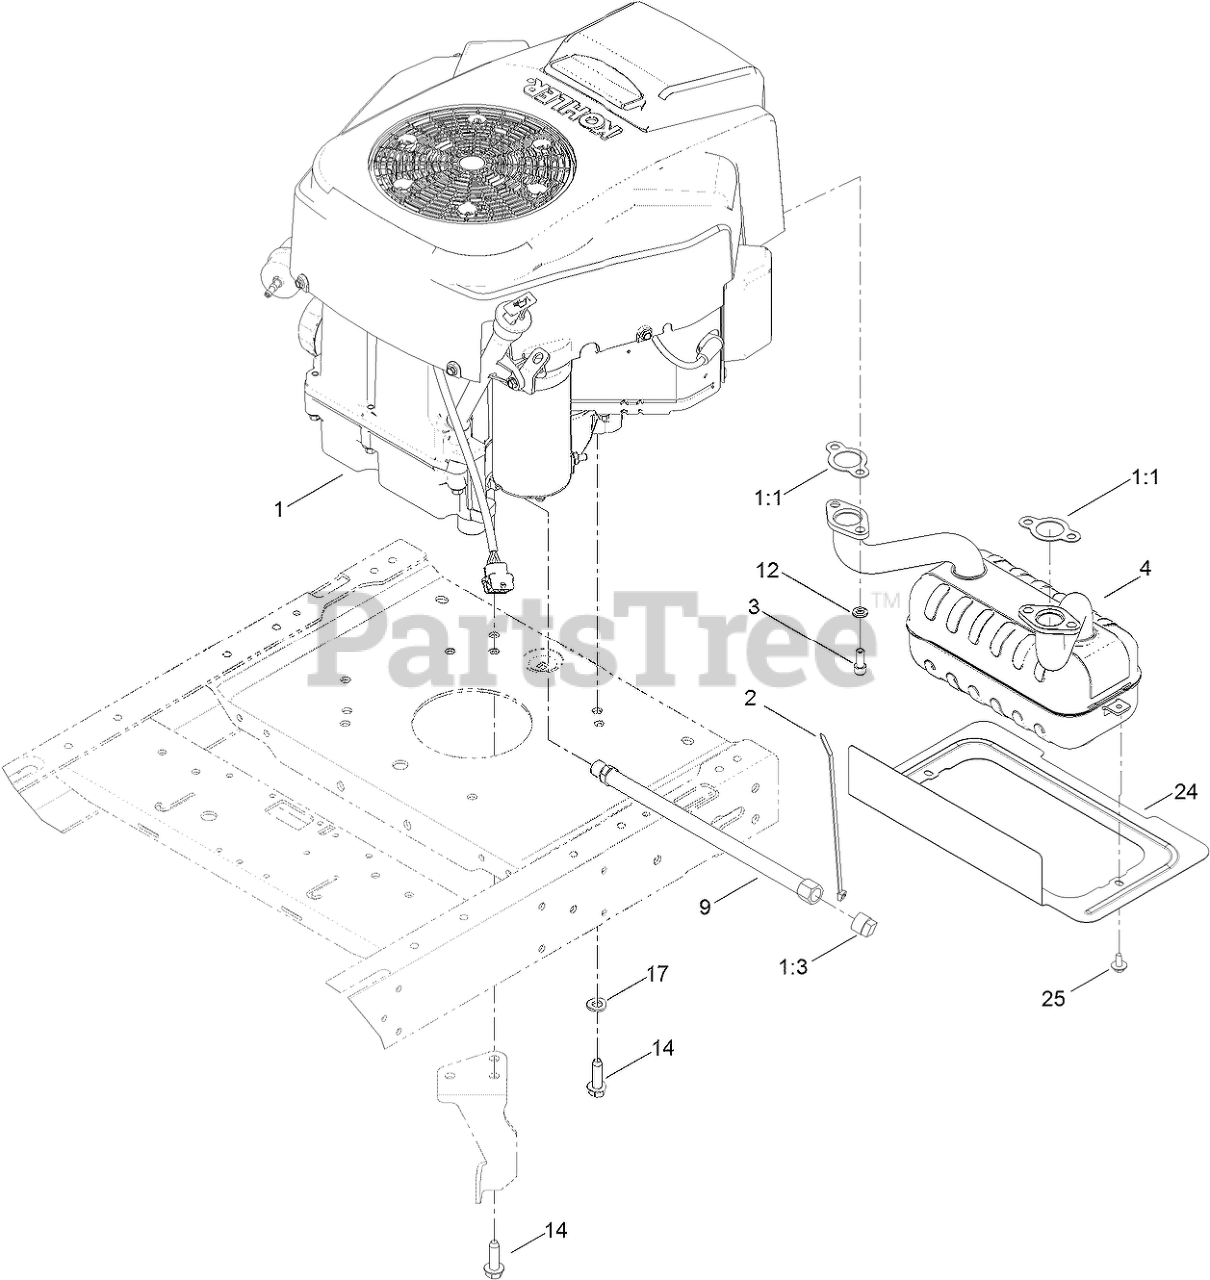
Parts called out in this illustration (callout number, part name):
1	ENGINE KOHLER - 7000 SERIES TWIN
1:1	GASKET-EXHAUST
1:3	PLUG-PIPE, SQH
2	TIE-CABLE
3	SCREW-HSH
4	MUFFLER-KOHLER
9	HOSE-DRAIN, OIL
12	WASHER-LOCK
14	SCREW-TAPTITE
17	WASHER-FLAT
24	SHIELD-HEAT
25	SCREW-HHFTF
